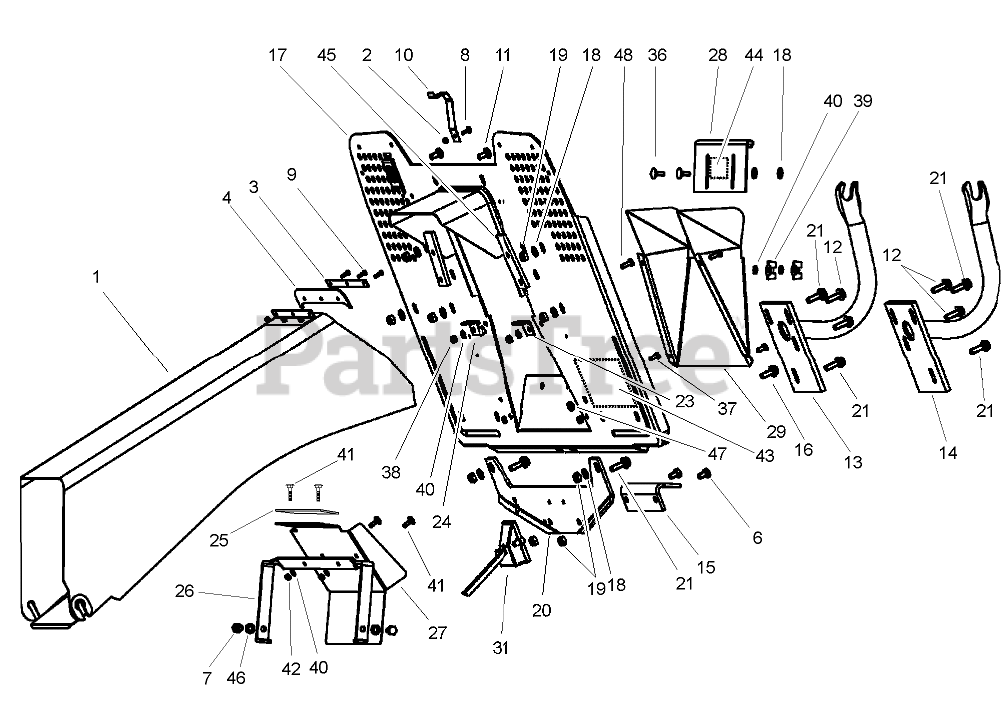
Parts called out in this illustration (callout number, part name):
1	Tunnel
2	NUT-HEX
3	PLATE-SUPPORT
4	SEAL-RUBBER
6	SCREW-HH
7	SCREW-HHF
9	SCREW-SFH
10	COVER-SWITCH
11	BOLT-CARRIAGE
13	SUPPORT-COLLECTOR, RIGHT
14	SUPPORT-COLLECTOR, LEFT
15	HITCH-TOW
16	SCREW-HEX
17	COLLECTOR PLATE ASM
18	WASHER-FLAT
19	NUT-LOCK, NI
20	SUPPORT-HITCH, TOW
21	SCREW-HEX
23	Support-Tunnel, Left
24	Support-Tunnel, Right
25	Shield-Rubber
26	BRACKET-SHIELD, PROTECTIVE
27	SHIELD-PROTECTIVE
28	Shield-Adjustable
29	Hopper-Receiving
31	OVERLOAD SWITCH ASM
37	SCREW-HH
38	NUT-LOCK
39	NUT-WING
40	WASHER-FLAT
41	BOLT-CARRIAGE
42	NUT-LOCK
43	DECAL-BYPASS, HYDRO
44	DECAL-POSITION, BAGGING
45	Plate-Reinforcing
46	Washer-Spring
47	Bushing
48	Screw-HH
